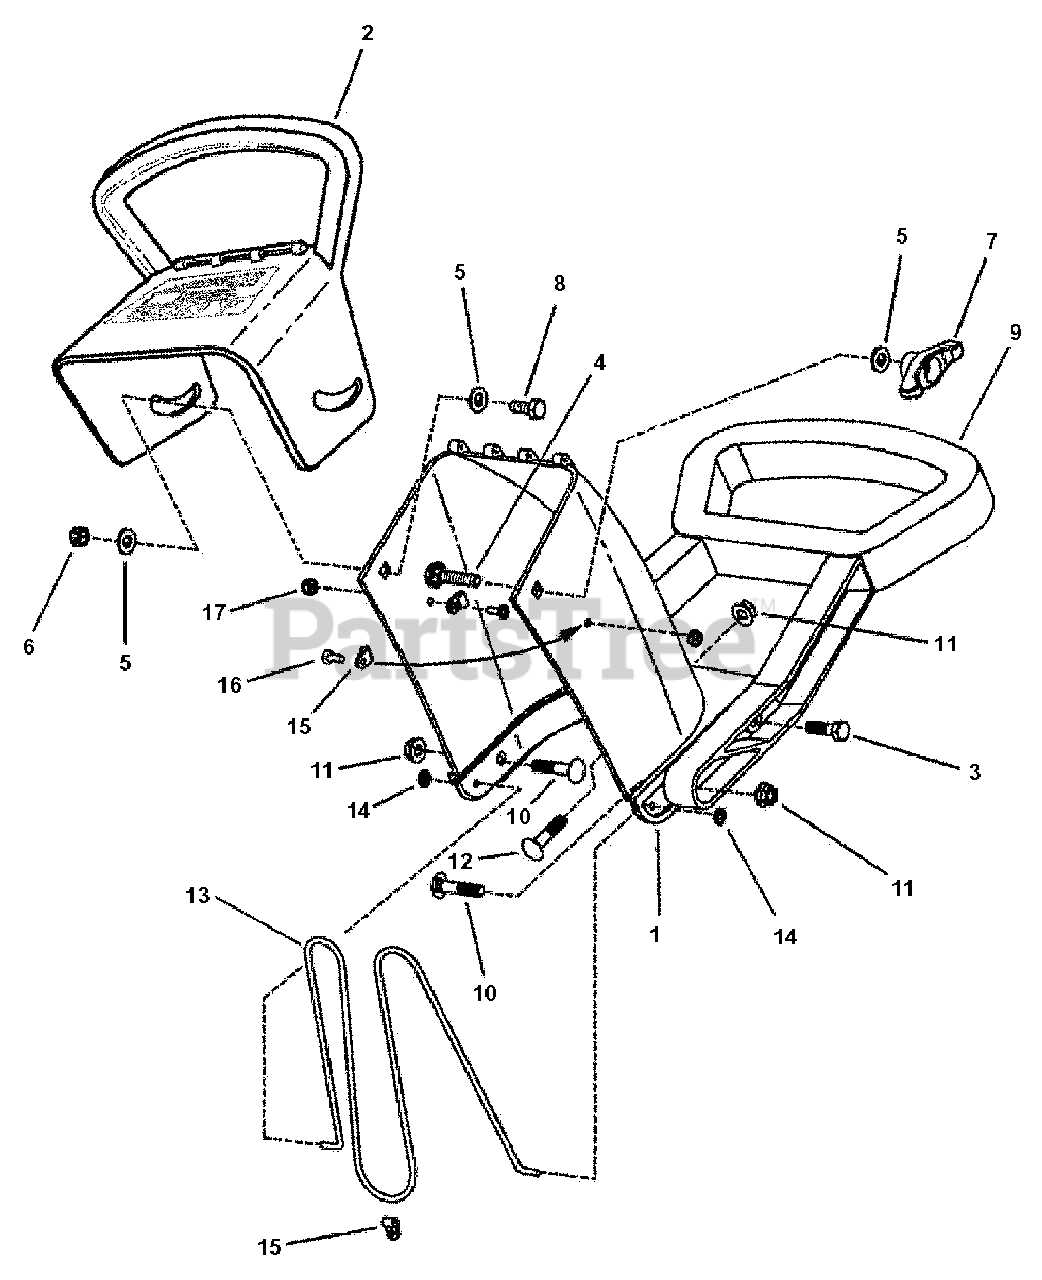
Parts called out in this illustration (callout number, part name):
1	CHUTE, Discharge, with inserts
2	DEFLECTOR, Chute (Includes Decal # 7024844)
3	SCREW, 5/16-18 x 3/4" Hex Head Cap, Grade 2
4	BOLT, 5/16-18 x 1" Short Neck Carriage, Grade 5
5	WASHER, 5/16 Flat
6	NUT, 5/16-24 Hex Center Lock, Grade B
7	KNOB, 5/16-18 Wing, Black
8	SCREW, 5/16-24 x 3/4" Hex Head Cap, Grade 5
9	HANDLE, Chute Control
10	CARRIAGE BOLT, 5/16-18 x 1-1/2"
11	NUT, 5/16-18 Hex Flange Lock, Grade 5
12	BOLT, 5/16-18 x 3/4" Short Neck Carriage, Grade 5
13	WIRE, Safety
14	FASTENER, Push On .156 Internal Diameter
15	CLIP, Guard, Tinnerman #C2980
16	SCREW, #8-32 x 1/2 Pan Head Cross Recess
17	NUT, #8-32 Hex, with free spinning external lock washer
